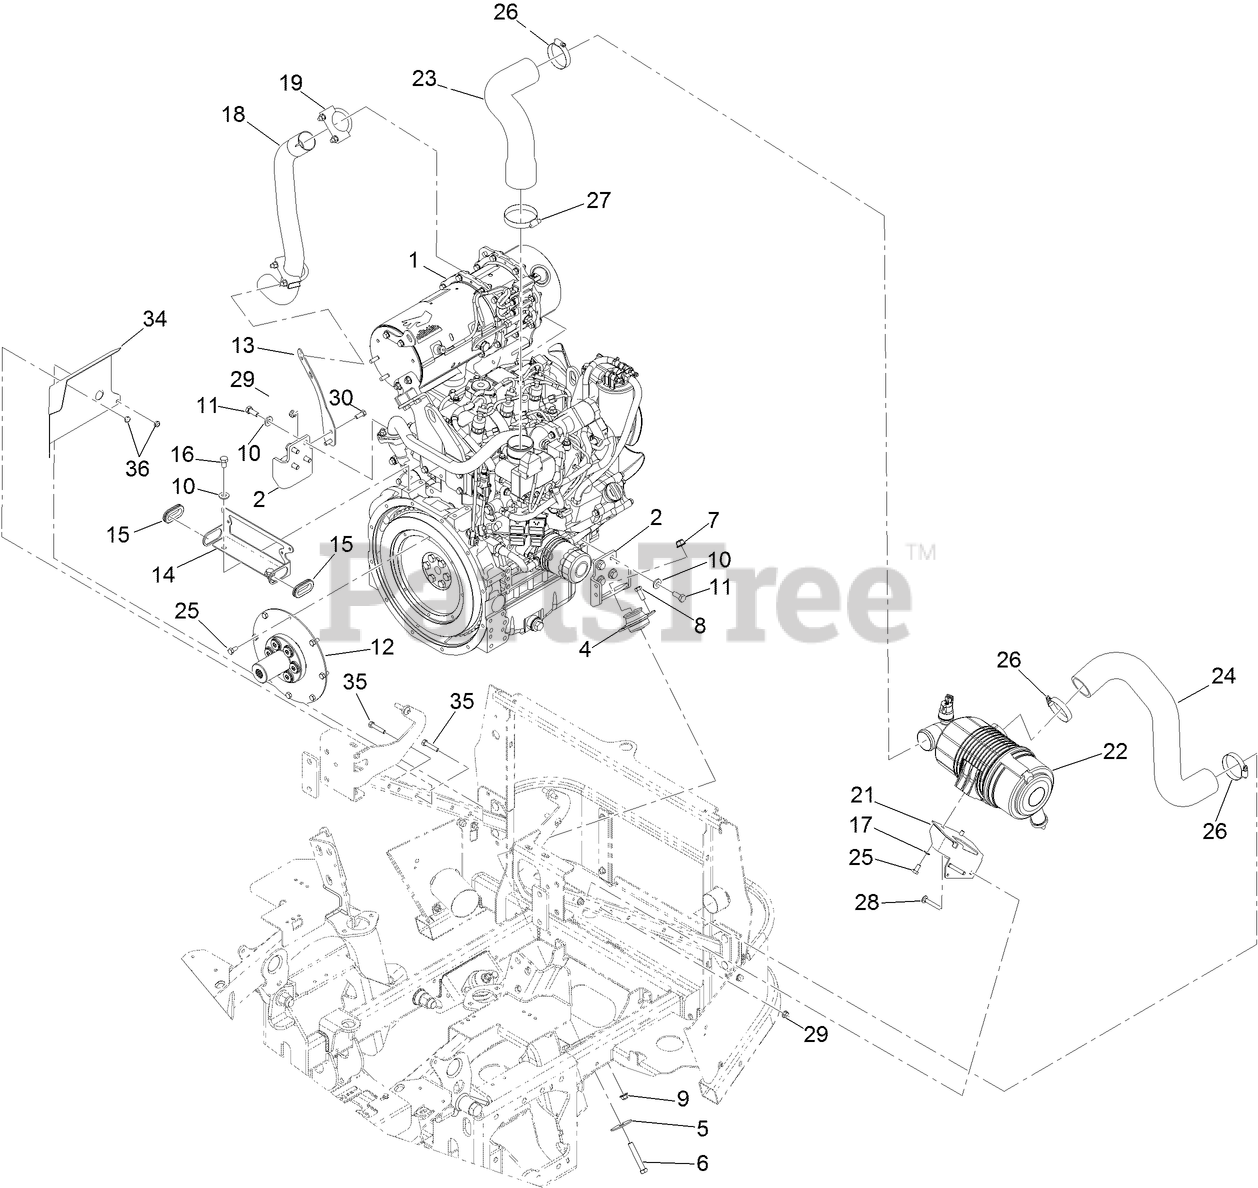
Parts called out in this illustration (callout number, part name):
1	ENGINE-YANMAR, 3TNV88C-DTR5
2	MOUNT-MOTOR, UPPER
5	WASHER-SNUBBING
6	SCREW-HH
7	NUT-HF, NI
8	SCREW-HH
9	NUT-HF, NI
10	WASHER-BELLEVILLE
11	SCREW-HH
12	COUPLING-FLYWHEEL
13	BRACKET-MOUNT
14	BRACKET-GUIDE
15	GROMMET-RUBBER
16	SCREW-HH
17	WASHER-BELLEVILLE
18	TUBE-EXHAUST
19	CLAMP
21	BRACKET-CLEANER, AIR
22	AIR CLEANER ASM
23	HOSE-AIR
24	HOSE-AIR
25	BOLT
26	CLAMP-HOSE
27	CLAMP-HOSE
28	BOLT-CARR
29	NUT-HF, NI
30	SCREW-HH
34	DEFLECTOR-AIR
35	SCREW-HH
36	NUT-LOCK, NI
